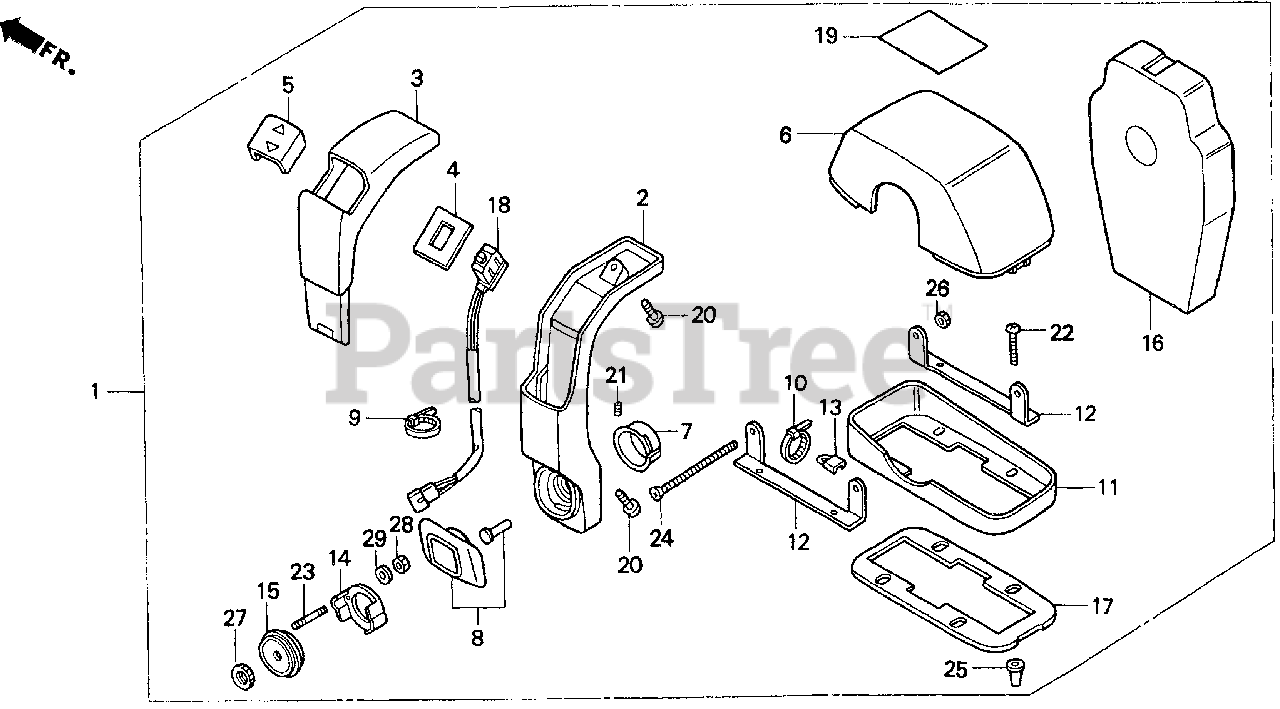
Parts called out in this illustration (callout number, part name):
1	BOX ASSY., REMOTE CONTROL (TOP MOUNT SINGLE) (NA USE ALT:24800-ZW7-V01) Use up to Frame SN 1000620.
2	HANDLE, REMOTE CONTROL Use up to Frame SN 1000620.
3	GRIP, REMOTE CONTROL HANDLE Use up to Frame SN 1000620.
4	PLATE, SWITCH SETTING Use up to Frame SN 1000620.
5	COVER, GRIP Use up to Frame SN 1000620.
6	HOUSING ASSY., REMOTE CONTROL BOX (A) (NOT AVAILABLE) Use up to Frame SN 1000620.
7	BUSHING Use up to Frame SN 1000620.
8	BUTTON ASSY. Use up to Frame SN 1000620.
9	BAND A, CABLE Use up to Frame SN 1000620.
10	BAND B, CABLE Use up to Frame SN 1000620.
11	HOUSING ASSY., REMOTE CONTROL BOX (B) Use up to Frame SN 1000620.
12	BRACKET, REMOTE CONTROL HOUSING Use up to Frame SN 1000620.
13	ANCHOR Use up to Frame SN 1000620.
14	BRACKET, SWITCH MOUNTING Use up to Frame SN 1000620.
15	PLATE ASSY., SWITCH MOUNTING Use up to Frame SN 1000620.
16	HOUSING ASSY. (INNER) (TOP MOUNT) Use up to Frame SN 1000620.
17	GASKET Use up to Frame SN 1000620.
18	SWITCH ASSY., POWER TRIM-TILT (A) Use up to Frame SN 1000620.
19	MARK, REMOTE CONTROL (SINGLE) Use up to Frame SN 1000620.
20	SCREW (10-32X1") Use up to Frame SN 1000620.
21	SCREW SET (1/4-20X16") Use up to Frame SN 1000620.
22	SCREW (10-32X1-1/2") Use up to Frame SN 1000620.
23	STUD (10-32X2") Use up to Frame SN 1000620.
24	SCREW (10-32X2-1/4") Use up to Frame SN 1000620.
25	NUT, WELDING (10-32) Use up to Frame SN 1000620.
26	NUT (10-32) Use up to Frame SN 1000620.
27	NUT, LOCK (15/32-32) Use up to Frame SN 1000620.
28	NUT (10-32) Use up to Frame SN 1000620.
29	WASHER Use up to Frame SN 1000620.
